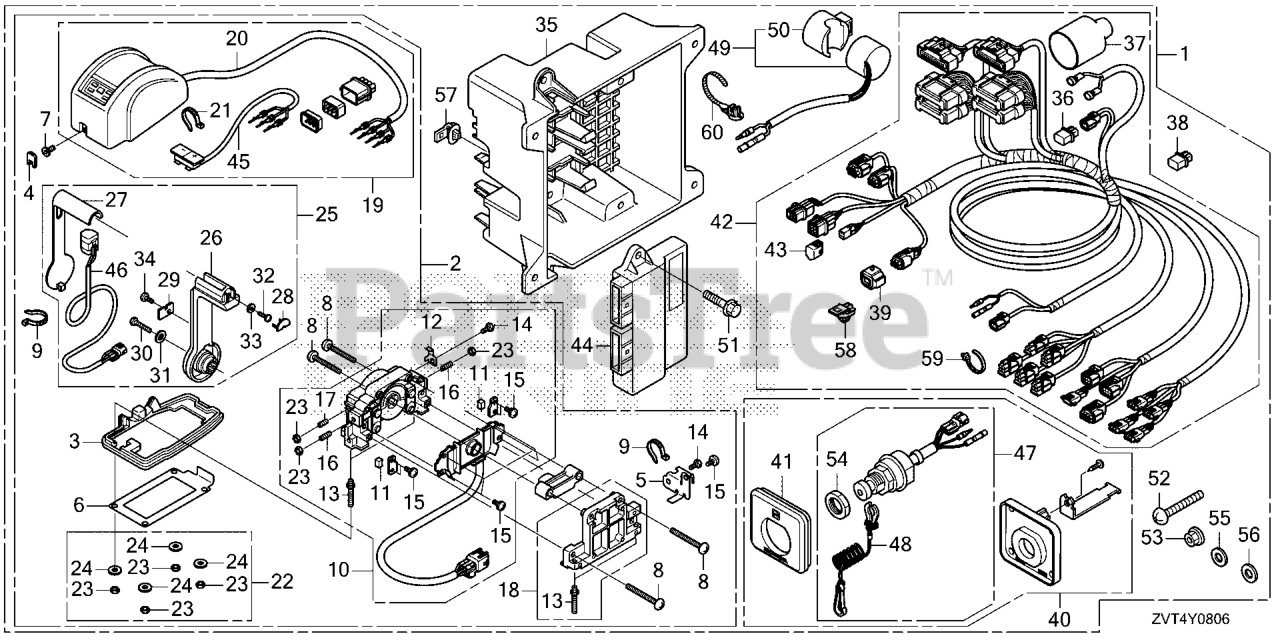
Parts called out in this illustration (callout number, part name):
1	BOX KIT, R/C (2ND)
2	BOX ASSY., REMOTE CONTROL (TOP MOUNT SINGLE)(RH)
3	GASKET (SINGLE)
4	COVER, CAP
5	PLATE, COVER FIX (SINGLE)
6	SHEET, WATERPROOF (SINGLE)
7	BOLT, SOCKET
8	SCREW
9	BAND, NYLON
10	HOUSING ASSY., L.
11	SHOE, BRAKE
12	PLATE, HARNESS
13	BOLT, STUD
14	BOLT
15	SCREW
16	SCREW SET
17	SCREW SET
18	HOUSING ASSY., SINGLE
19	COVER ASSY., SINGLE
20	LED ASSY., COVER (S)
21	BAND, NYLON
22	NUT SET, MOUNTING
23	NUT
24	WASHER
25	LEVER ASSY., L.
26	LEVER
27	PANEL, LEVER (POWER TRIM-TILT)
28	CAP, LEVER
29	PLATE, LEVER PANEL
30	BOLT
31	WASHER
32	SCREW
33	WASHER
34	SCREW
35	CASE, CONTROL UNIT
36	TERMINATOR ASSY.
37	COVER, CONNECTOR (NOT AVAILABLE)
38	DUMMY, WATERPROOF CONNECTOR
39	SUSPENSION, CONNECTOR
40	PANEL ASSY., EMERGENCY STOP
41	PANEL, EMERGENCY STOP SWITCH
42	CABLE ASSY., REMOTE CONTROL (2ND)
43	CAP, DUMMY (WPC 4P 090 M) (RED)
44	UNIT ASSY., CONTL
45	SWITCH ASSY., SELECT
46	SWITCH ASSY., POWER TRIM-TILT
47	SWITCH ASSY., EMERGENCY STOP
48	WIRE, EMERGENCY
49	BUZZER ASSY., WARNING
50	SUSPENSION, WARNING BUZZER
51	BOLT, FLANGE (6X20)
52	SCREW, PAN (5X40) DUAL QTY = (8) (SINGLE)
53	NUT, FLANGE (5MM)
54	NUT
55	WASHER, PLAIN (5MM)
56	WASHER, SPG (5MM)
57	CLIP, CONNECTOR (DARK BLUE)
58	CLIP, CONNECTOR (DARK BROWN)
59	CLIP, HARNESS BAND (145MM) (BLACK)
60	CLIP, BAND HARNESS (152.4MM) (BLACK)
